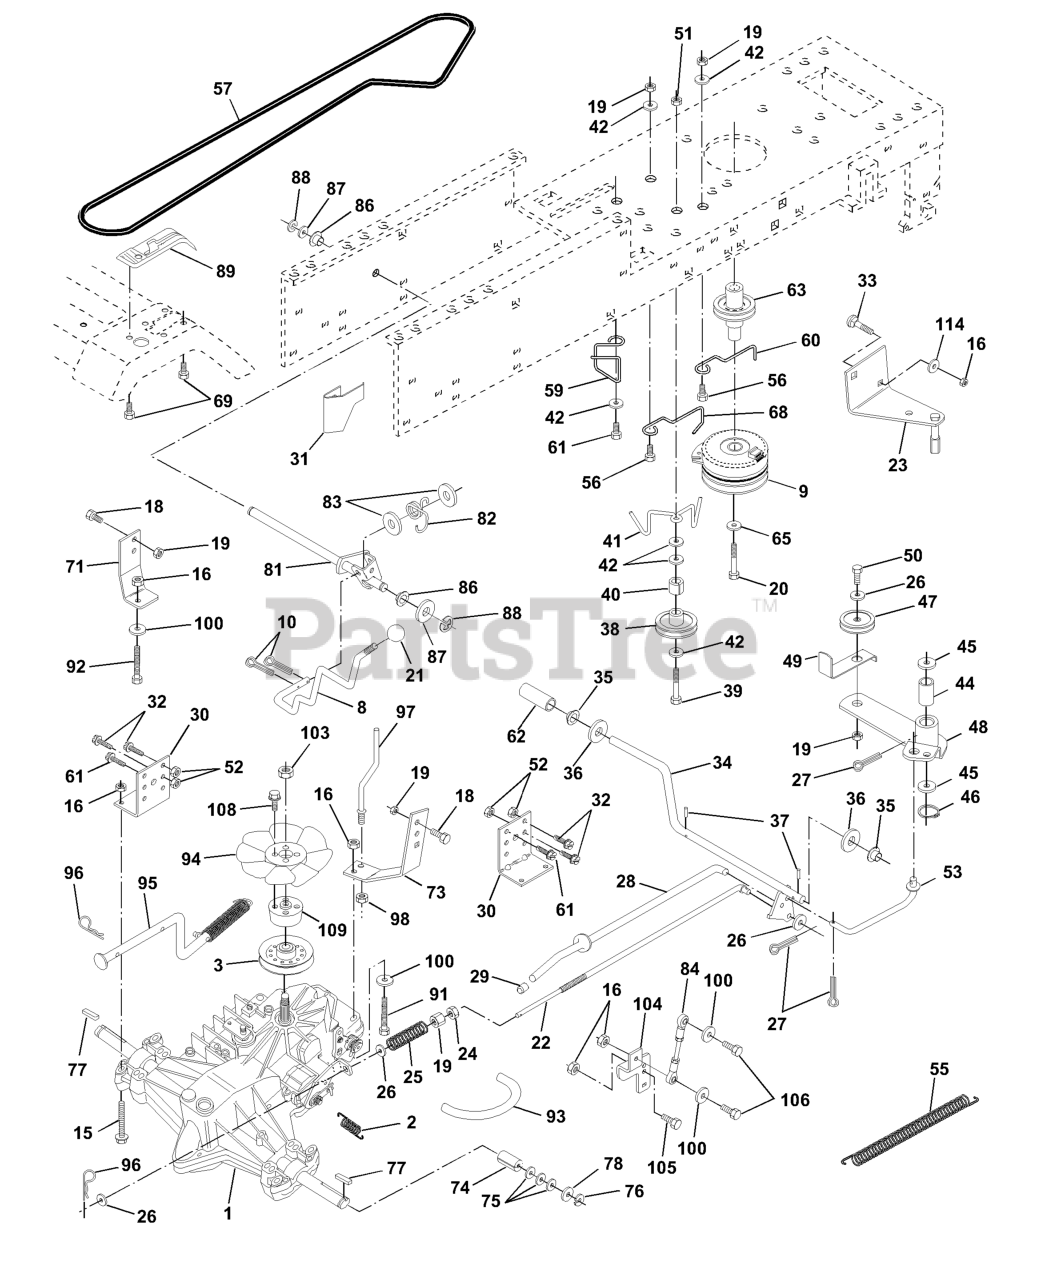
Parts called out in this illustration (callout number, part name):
1	TRANSAXLE.HYDRO.319-0500.LR
2	SPRING BRAKE
3	PULLEY.4.20.HYDRO
9	CLUTCH.ELECT.EVX.
10	PIN COTTER
15	BOLT HEX 5/16-18 GR 5
16	NUT.71038.31-18.HEX.NYLOCK
18	BOLT
19	NUT
20	BOLT HEX
21	KNOB.DUCKHEAD.1/2
22	ROD BRAKE HYDRO
23	CLUTCH MTG BRACKET
24	NUT
25	SPRING ROD LT
26	WASHER
27	COTTER PIN
28	ROD BRAKE PARK LT
29	PLUNGER CAP
30	BRACKET TRANSAXLE
31	KEEPER BELT LH
32	BOLT
33	RP BOLT 5/16-18 X3/4 ZN/YEL GR
35	BEARING.NYLON
36	WASHER LT
37	DRIVE PIN
38	PULLEY.IDLER.FLAT
41	BELT GUIDE
42	WASHER
44	BEARING LT (2 2)
47	IDLER PULLEY
49	RETAIN BELT
50	BOLT
52	LOCKNUT
53	LINK, CLUTCH LT
55	SPRING, RETURN LT
59	KEEPER CENTER SPAN
60	KEEPER,BLT ENG LT
61	SCREW
62	PEDAL COVER T
63	PULLEY, CLUTCH ELECT EVX
65	LOCKWASHER
68	KEEPER BELT ENGLH
69	SCREW.HI-LO.CONSOLE
71	STRAP TORQUE LH HYDRO
73	STRAP TORQUE RH HYDRO
74	SPACER SPLIT
77	SQUARE KEY
82	SPRING,TORSION
83	WASHER
84	ROD, TIE HYDRO
86	BUSHING.STEERING.ROD LTB-WSL
91	BOLT.FIN HEX 5/16-18UNC X2 1/4
92	HEX BOLT
93	LINE FUEL HYD 4"
94	FAN 7" HYDRO
95	CONTROL ARM, BYPASS HYDRO
96	RETAINER M
97	KEEPER BELT RH
100	WASHER M
103	NUT.HEX.1/2-20
104	ARM, CONTROL HYDRO
106	BOLT.5/16-18X1-1/4 FULL.THREAD
109	ADAPTOR FAN HYDRO
114	Washer 11/32 x 3/4 x 14 Ga.
